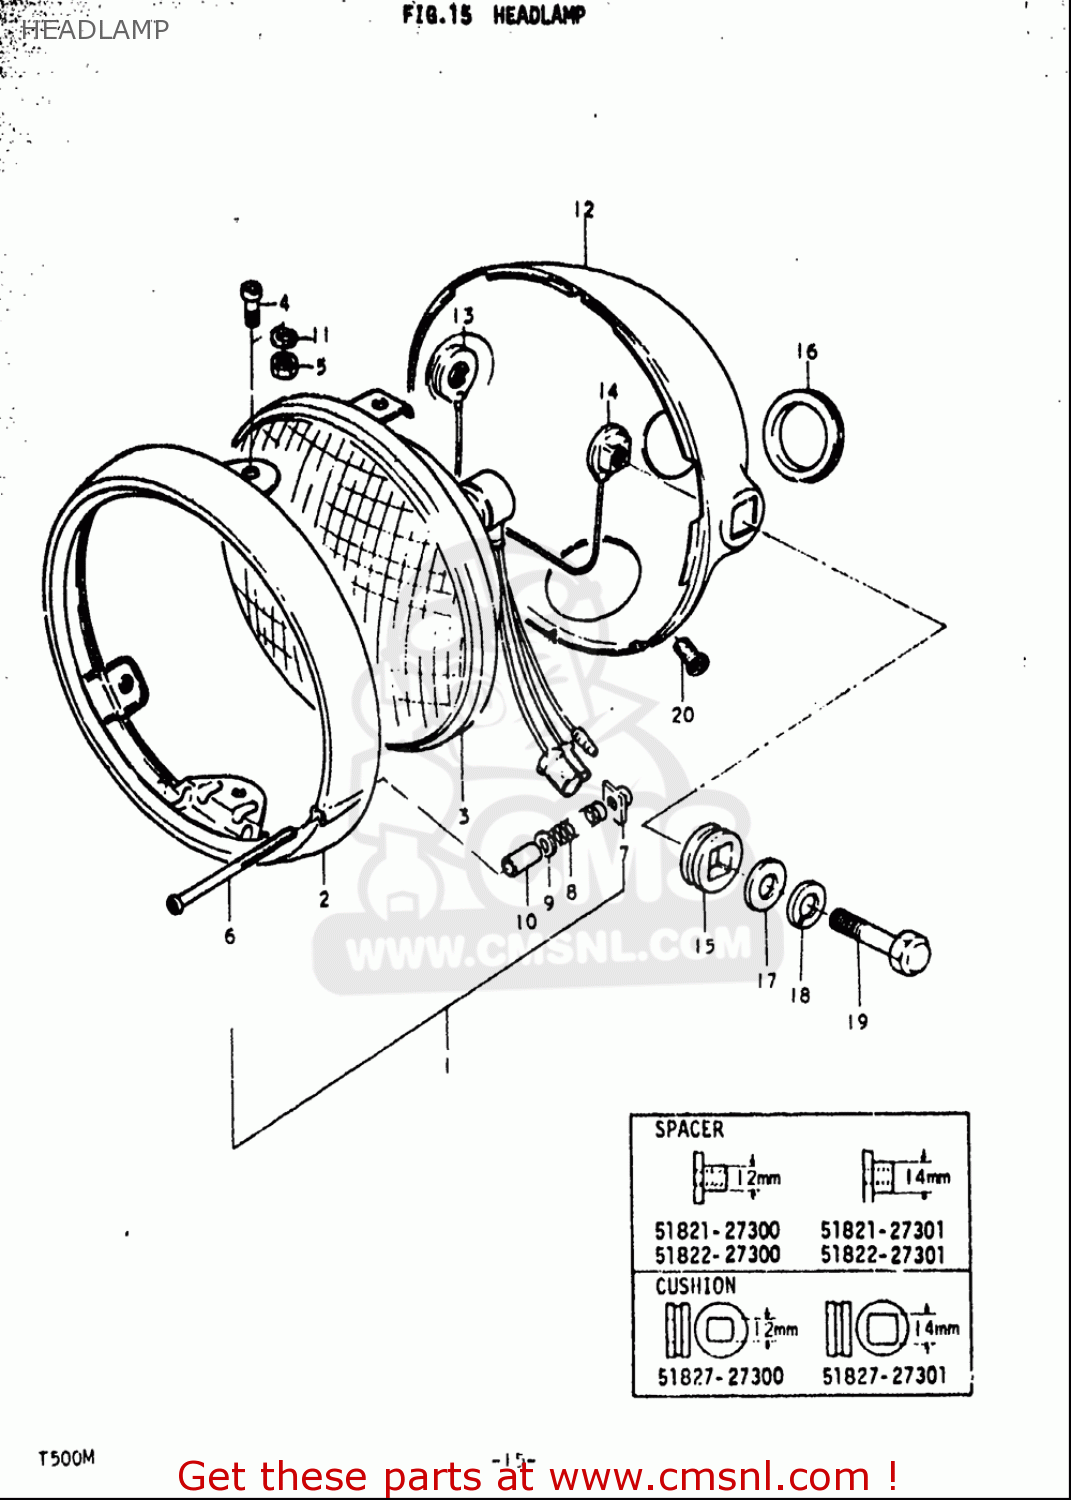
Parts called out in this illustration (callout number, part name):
4	H/LAMP LENS UNIT FITING SCRE
5	NUT
6	SCREW
7	NUT
9	WASHER
11	WASHER,LOCK
15	CUSHION,HEADLAMP HOUSING
17	WASHER
18	WASHER,LOCK
19	BOLT
20	SCREW
